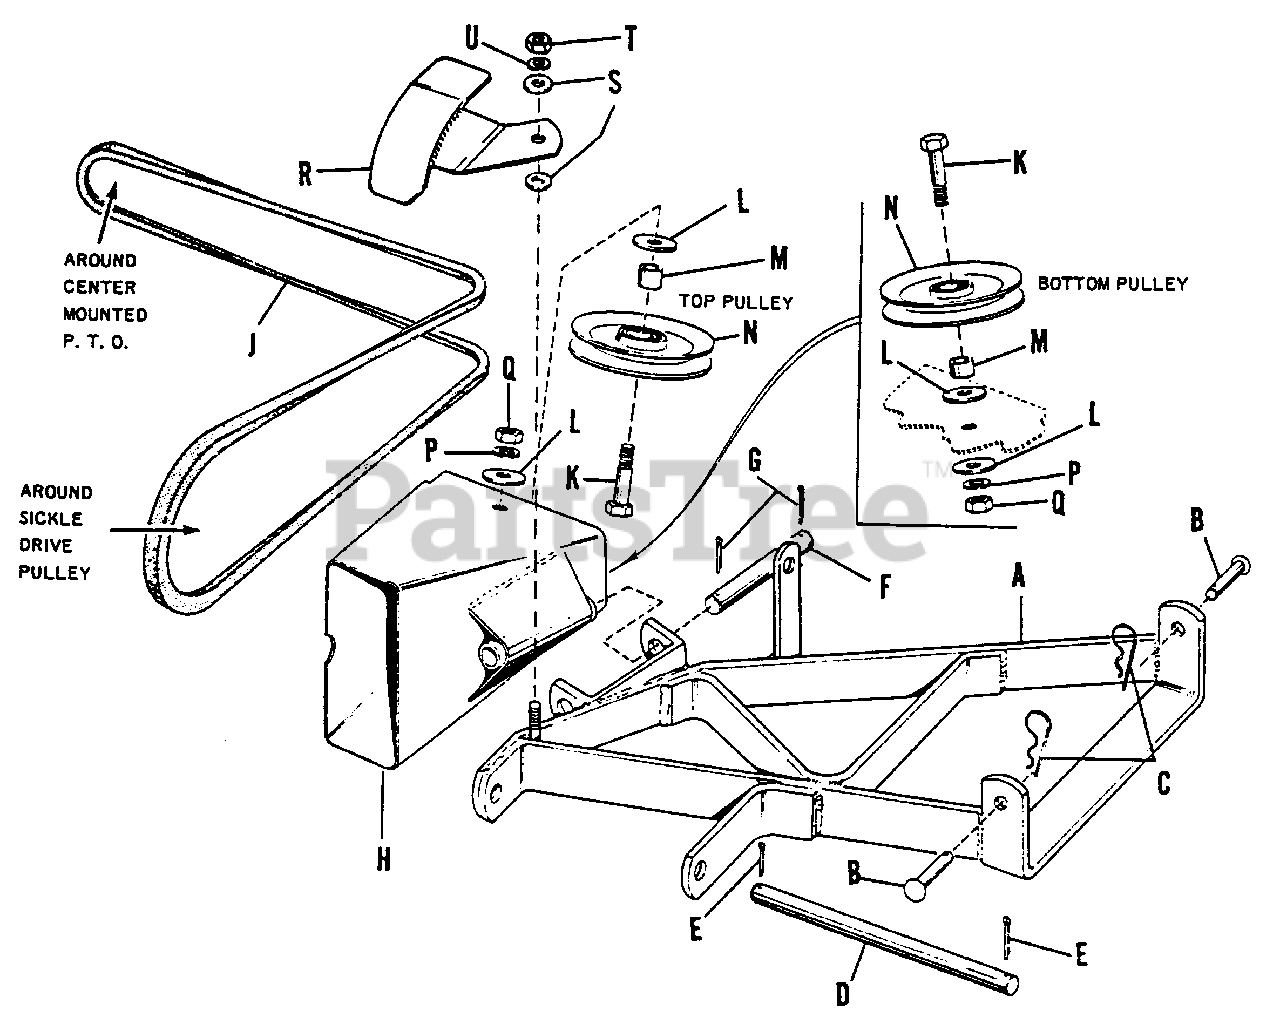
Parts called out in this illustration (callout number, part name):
A	Frame Assembly
B	Pin
C	Clip, Spring
D	Shaft, Hinge
E	Pin, Cotter, 3/16" x 1" lg.
F	Shaft. Idler Pulley Bracket
G	Pin, Cotter, 3/16" x 1" lg.
H	Guard Assembly, Belt
J	Belt, "V"
K	Capscrew, Hex Hd., 3/8"-16 NC x 1-3/4" lg.
L	Washer, Plain 3/8"
N	Pulley, Idler (w/ball bearing)
P	Lockwasher, 3/8"
Q	Nut, Hex, Full 3/8"-16 NC
R	Guard Assembly Belt
S	Washer Plain
T	Nut, Hex, Full, 3/8"-16 NC
U	Washer Lock 3/8"
